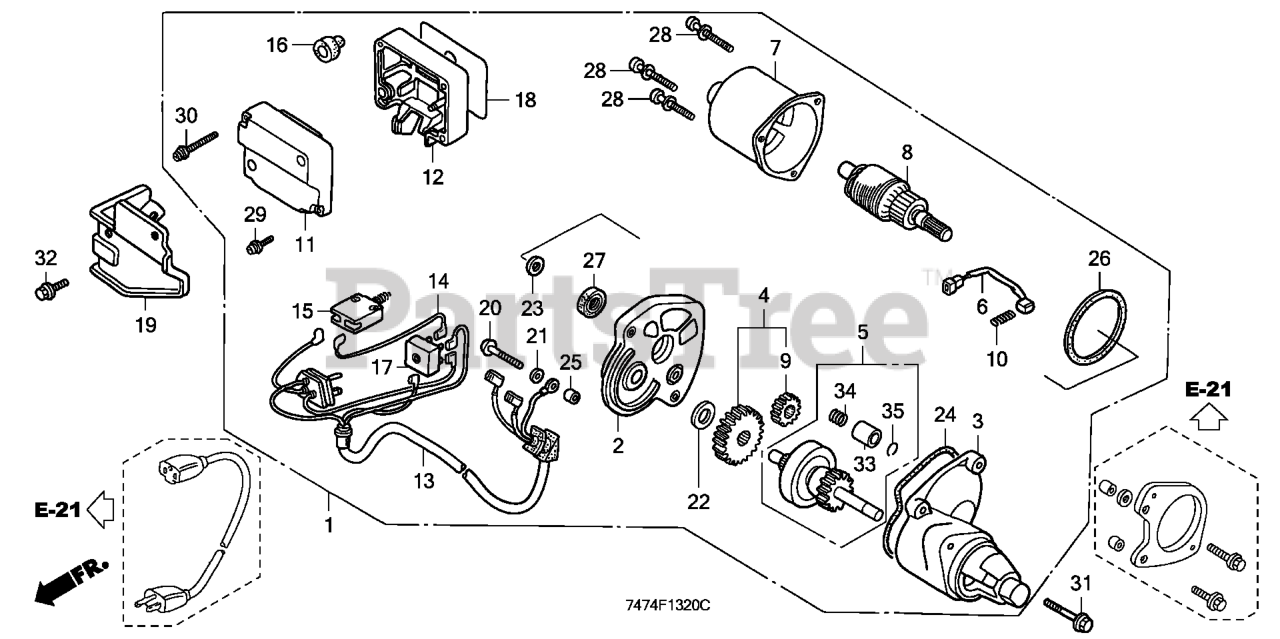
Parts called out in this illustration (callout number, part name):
1	MOTOR ASSY., STARTER
2	HOUSING, CENTER Use from Engine SN 2056820.
3	HOUSING, PINION Use from Engine SN 2056820.
4	GEAR, REDUCTION Use up to Engine SN 2056819.
5	CLUTCH Use from Engine SN 2056820.
6	BRUSH Use from Engine SN 2056820.
7	YOKE Use from Engine SN 2056820.
8	ARMATURE Use from Engine SN 2056820.
9	GEAR, DRIVE Use up to Engine SN 2056819.
10	SPRING, BRUSH RETURN Use from Engine SN 2056820.
11	COVER Use from Engine SN 2056820.
14	SUB-WIRE Use up to Engine SN 2056819.
15	SWITCH, STARTER (Honda Code 2299584). (A.C. 380V-16A)
15	SWITCH, STARTER (Honda Code 2773141). (A.C. 250V-16A)
16	CAP Use up to Engine SN 2056819.
17	DIODE Use up to Engine SN 2056819.
18	PLATE, CAUTION (ENGLISH)
19	BRACKET, SWITCH BOX
20	SCREW, TRUSS (4X30) Use from Engine SN 2056820.
21	WASHER, STAR (4MM) Use from Engine SN 2056820.
22	WASHER (A) Use from Engine SN 2056820.
23	WASHER (B) Use from Engine SN 2056820.
24	O-RING Use from Engine SN 2056820.
25	COLLAR Use from Engine SN 2056820.
26	GASKET Use from Engine SN 2056820.
27	OIL SEAL Use up to Engine SN 2056819.
28	SCREW-WASHER (5X30) Use up to Engine SN 2056819.
29	SCREW-WASHER (4X20)
30	SCREW-WASHER (4X30)
31	BOLT, FLANGE (6X20)
32	BOLT, FLANGE (6X40)
33	STOPPER, PINION Use from Engine SN 2056820.
34	SPRING, COIL
35	RING, RETAINING Use from Engine SN 2056820.
